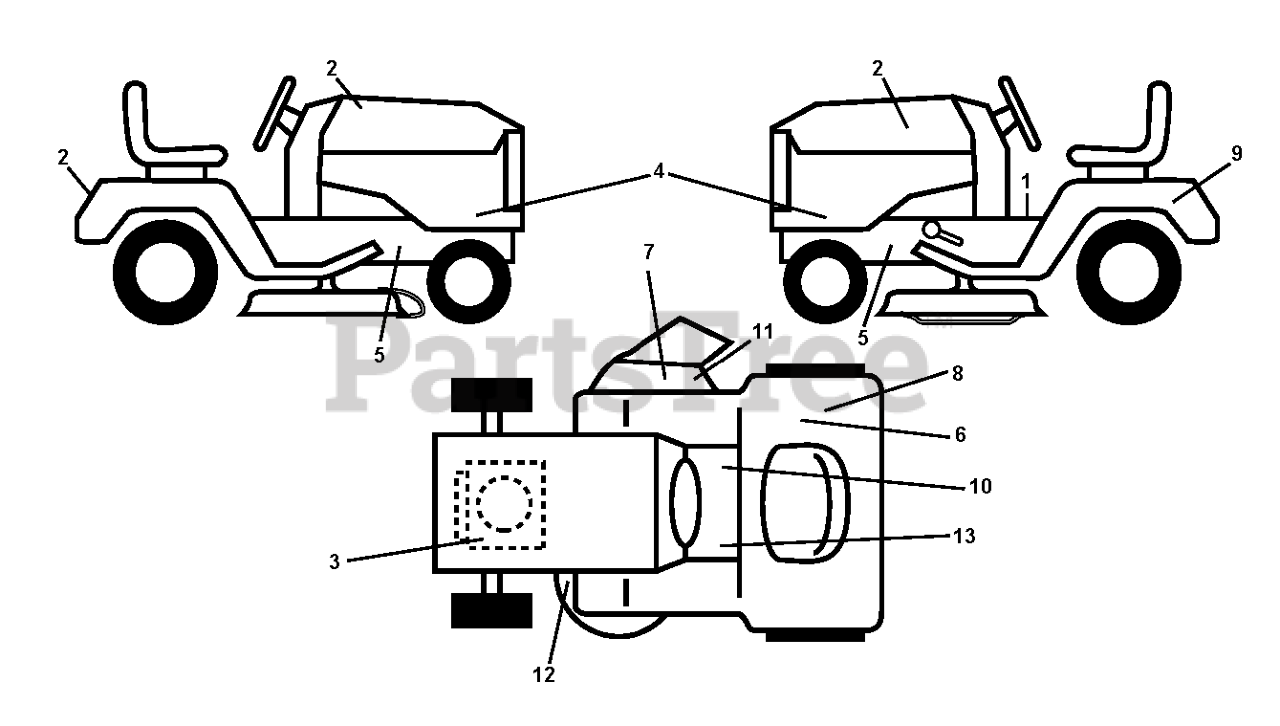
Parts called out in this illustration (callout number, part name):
1	LABEL
2	DECAL.HOOD.LOGO.ORANGE.HUSQVAR
3	DECAL
6	DECAL 80 DBA
7	DECAL.INTERNATIONL.CUTFINGER
8	DECAL
9	DECAL BTRY SYMBOLS
10	DECAL PARK BRAKE
11	DECAL, DEFLECT WARNING
12	DECAL.V-BELT.SCHEMATIC.36/38/9
13	DECAL
